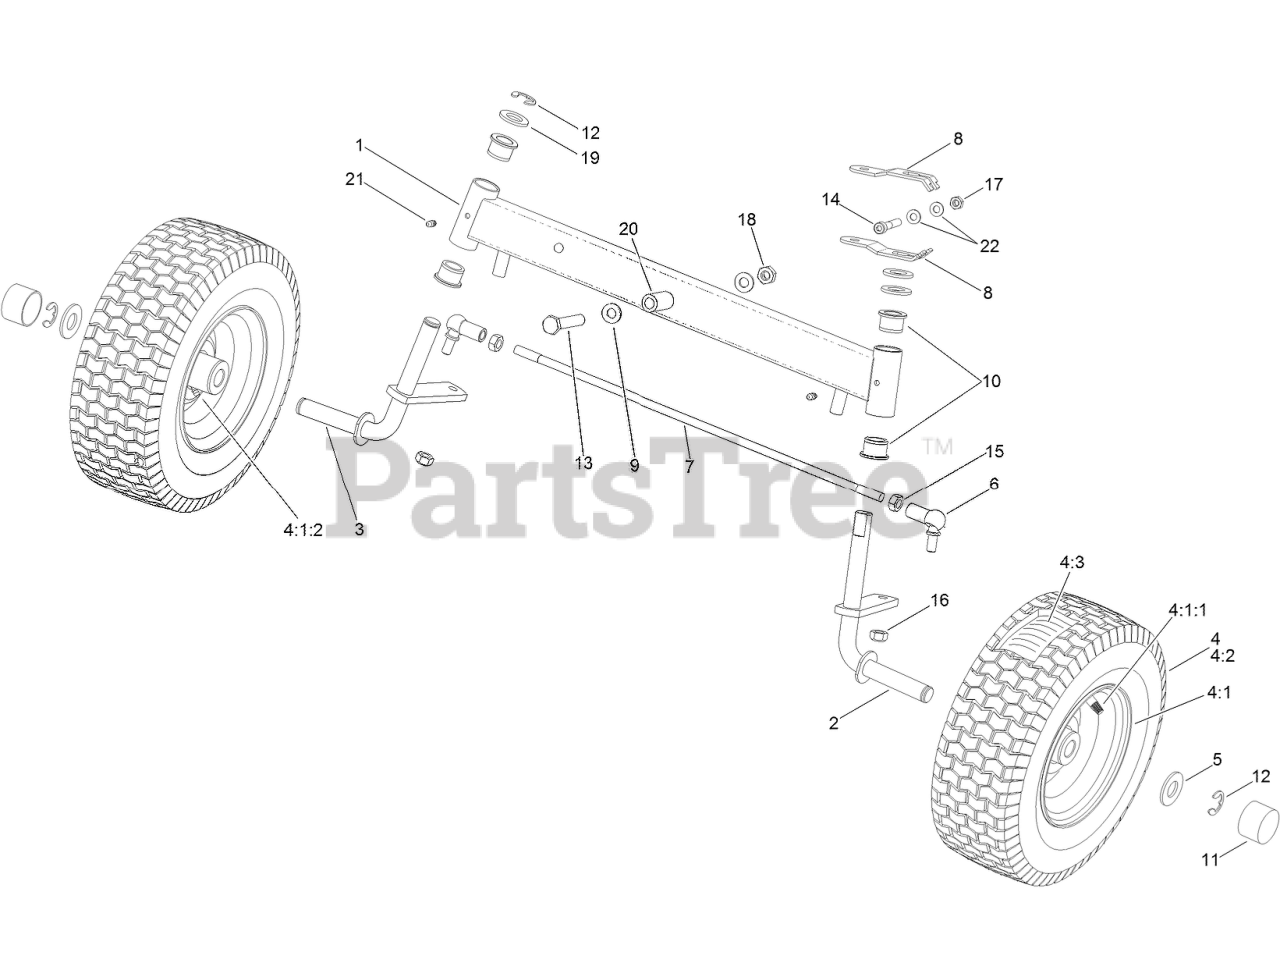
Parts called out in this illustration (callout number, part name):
1	FRONT AXLE ASM
2	SPINDLE-LH
3	SPINDLE-RH
4	WHEEL ASM
4:1	FRONT RIM ASM
4:1:1	Valve-Tire
4:1:2	FITTING-GREASE
5	WASHER
6	JOINT-BALL, ANGLE
7	TIE ROD-AXLE, FRONT
8	LEVER-SPINDLE, STEERING
9	SPACER
10	BUSHING-SWIVEL
11	CAP-HUB
12	CLIP-SPRING
13	SCREW-HH
15	NUT-HEX
16	Nut-Lock
17	NUT-LOCK, NI
18	NUT-LOCK, HEX NI
19	WASHER-FLAT
20	WASHER
21	FITTING-GREASE
22	WASHER-PLAIN
